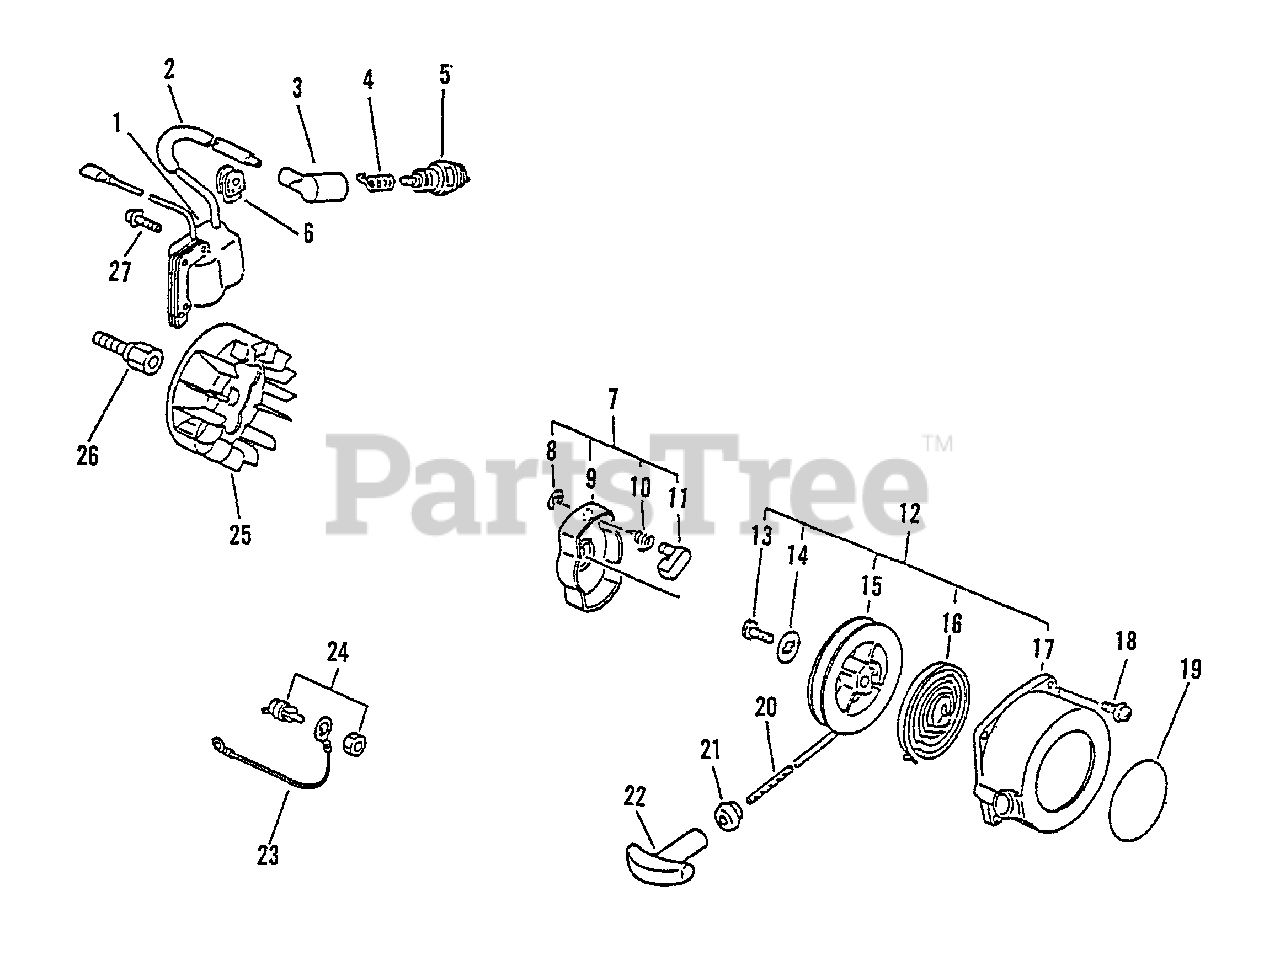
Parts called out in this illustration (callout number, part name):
1	COIL, IGNITION
3	CAP, SPARK PLUG
4	TERMINAL, SPARK PLUG CAP
5	SPARK PLUG -- BPM-7A
5	SPARK PLUG -- BPMR-7A
7	STARTER PAWL ASSY
8	RING, RETAINING - 4
9	CATCHER, PAWL
10	SPRING, RETURN
11	PAWL, STARTER
12	STARTER ASSY
14	WASHER
15	REEL, ROPE
16	SPRING, REWIND
17	CASE, STARTER
18	SCREW - 4X18
19	LABEL - ECHO
20	ROPE, STARTER - 3X1000
21	GUIDE, ROPE
22	GRIP, STARTER
23	LEAD - GROUND
24	IGNITION SWITCH ASSY
25	FLYWHEEL
26	HUB, FAN
27	SCREW - 4X22
